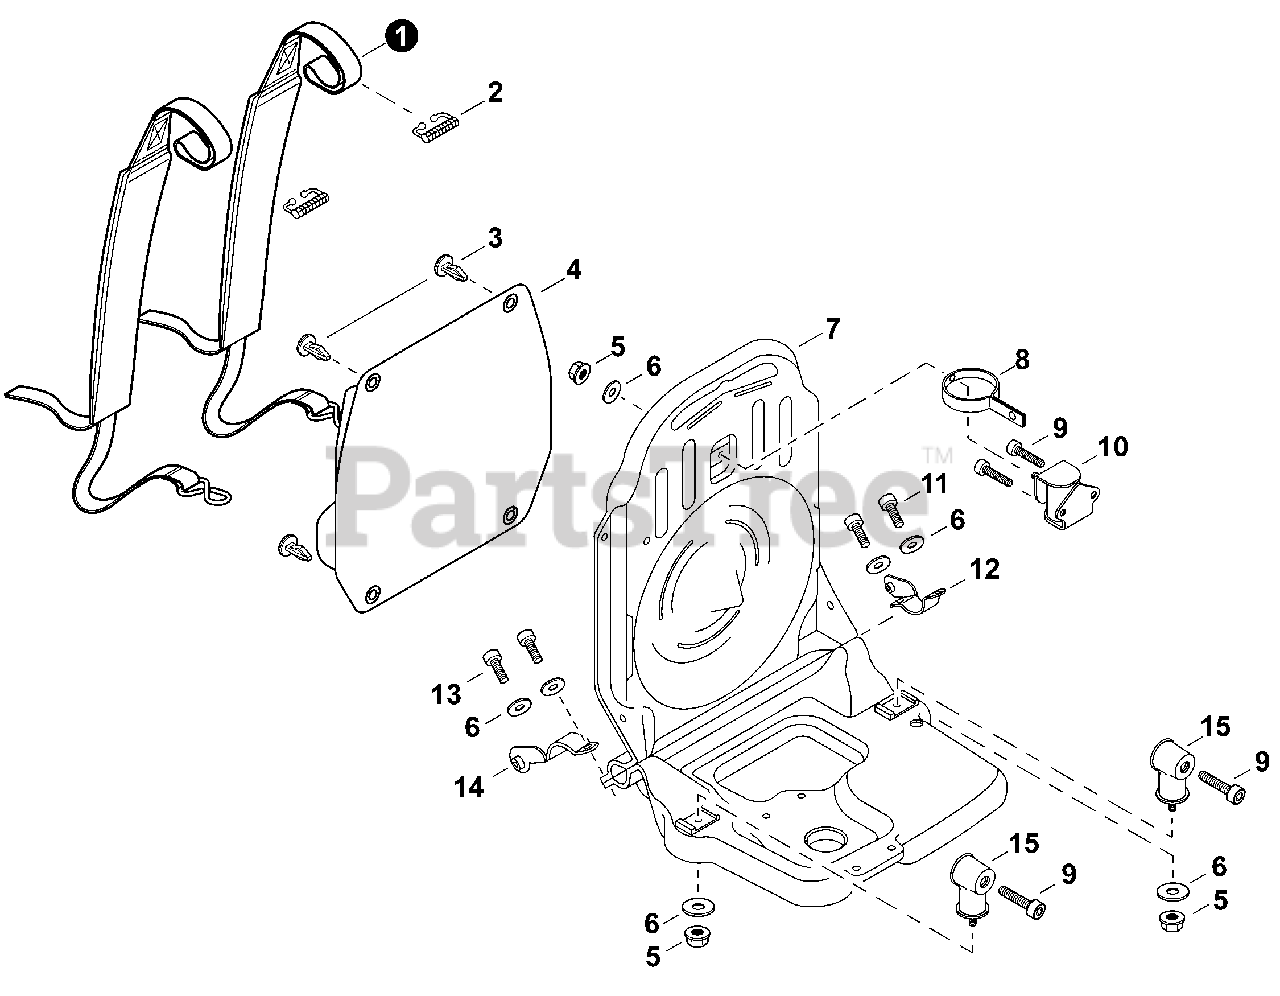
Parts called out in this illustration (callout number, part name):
1	HARNESS ASSY, BACKPACK
2	CLIP, HARNESS
3	CLIP 7/16"
4	CUSHION, BACKPACK
5	NUT, FLANGE M5
6	WASHER 5.5×16×2T
7	FRAME, BACKPACK
8	RETAINER
9	SCREW TAPPING 5×16
11	BOLT 5×20
12	CONNECTOR, HARNESS (B)
13	BOLT, TAPPING 5×25
14	BRACKET, HARNESS
15	CUSHION, FRAME 5
